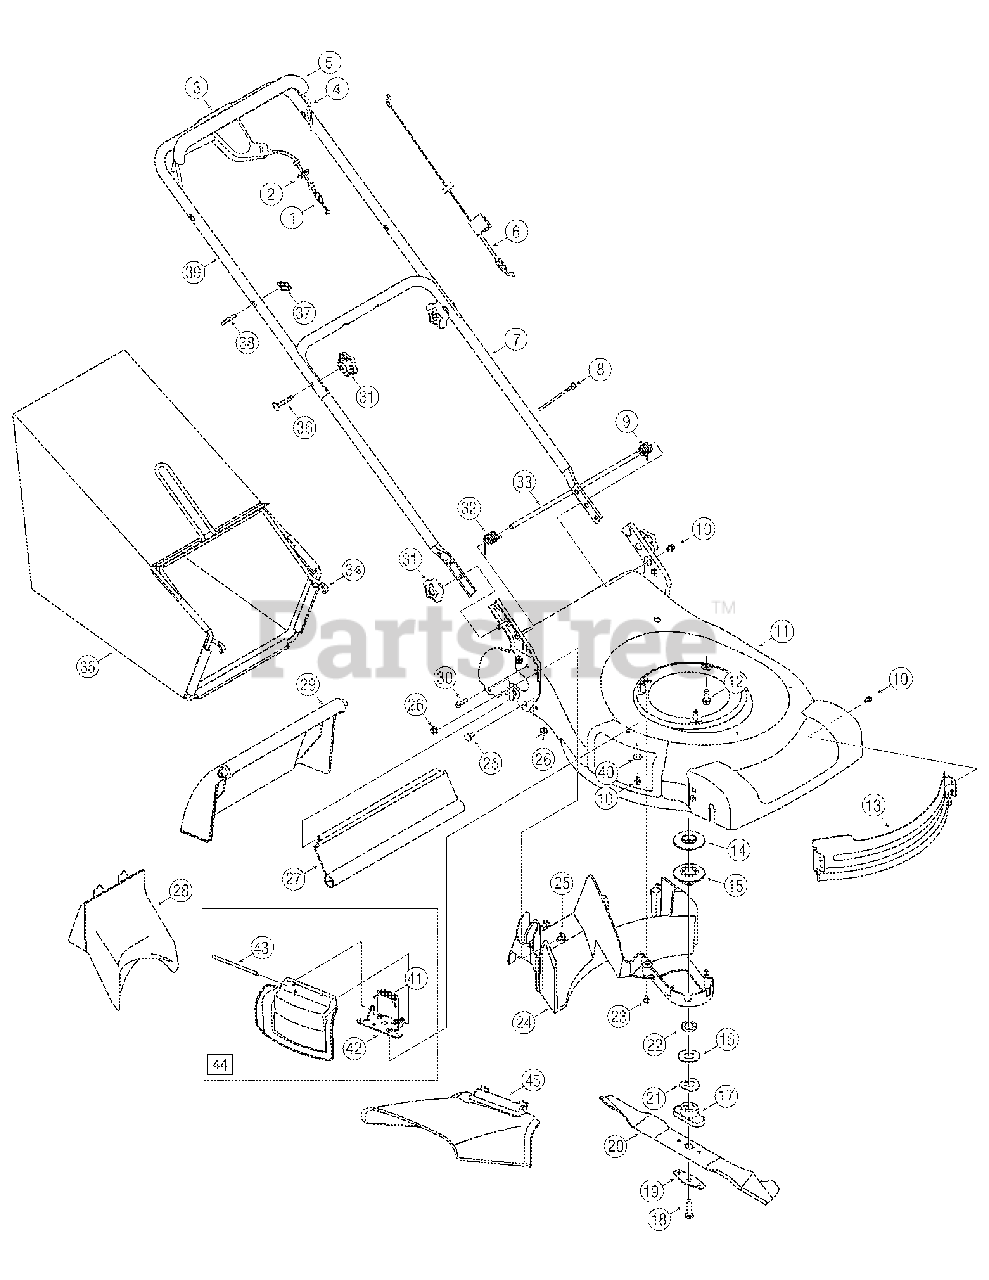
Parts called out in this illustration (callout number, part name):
1	Drive Cable
2	Rubber Grommet
3	Drive Control Assembly
5	Bail Cover
6	Control Cable
8	Cable Tie
9	Torsion Spring, LH
10	TT Screw, 1/4-20 x .500
12	TT Screw, 3/8-16 x 1.00
13	Deck Baffle
14	Upper Engine Pulley
15	Lower Engine Pulley
16	Flat Washer, .885 x 1.850 x .060
17	Blade Adapter
18	Screw, 3/8-24 x 1.50
19	Blade Bell Support
20	21-inch Mulching Blade
21	Spring Washer, .890 x 1.70 x .048
22	Sleeve Spacer
23	TT Screw, 1/4-20 x .375
24	Deck Baffle
25	Carriage Bolt, 5/16-18 x .62
26	Flange Lock Nut, 5/16-18
27	Trailshield
28	Mulch Plug
29	Rear Door
30	Screw, 1/4-15 x 1.00
31	Star Knob
32	Torsion Spring, RH
33	Door Pivot Rod
36	Carriage Bolt, 5/16-18 x 2.00
41	Torsion Spring
42	Chute Deflector Adapter
43	Hinge Pin
44	Mulch Plug Assembly
45	Side Discharge Chute
